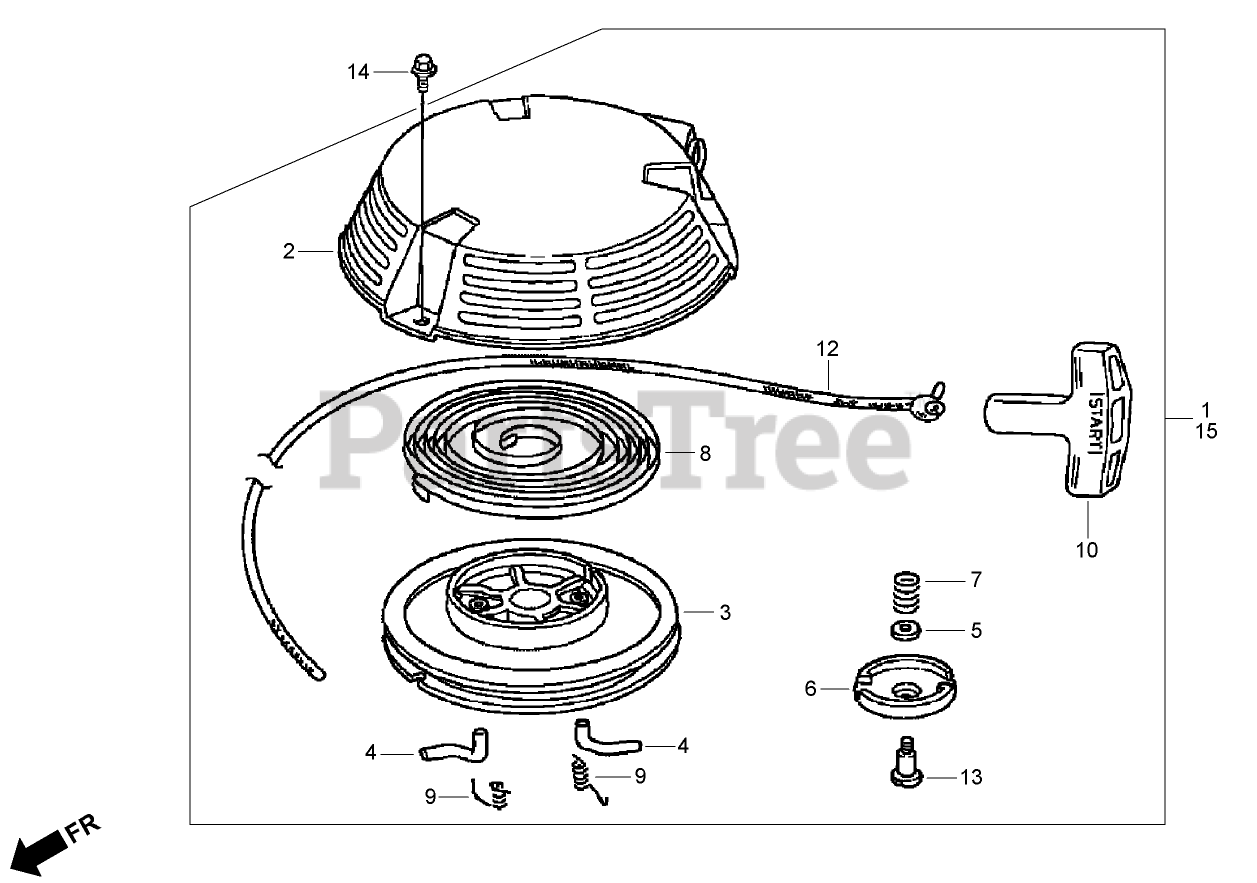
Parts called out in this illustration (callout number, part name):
1	RECOIL STARTER ASM-N H1 (LONG ROPE) (BLACK)
1	RECOIL STARTER ASM-R280 (LONG ROPE) (POWER RED)
2	CASE-STARTER, RECOIL R280 (POWER RED)
2	CASE-STARTER, RECOIL (N H1) (BLACK)
3	REEL-STARTER, RECOIL (BLACK)
4	RATCHET-STARTER
5	PLATE-FRICTION
6	GUIDE-RATCHET
7	SPRING-FRICTION
8	SPRING-STARTER, RECOIL
9	SPRING-RETURN
10	KNOB-STARTER, RECOIL
12	ROPE-STARTER, RECOIL
13	SCREW-SETTING
14	BOLT-FLANGE (6X8)
15	RECOIL STARTER ASM-R280 (LONG ROPE) (POWER RED)
15	RECOIL STARTER ASM-N H1 (LONG ROPE) (BLACK)
